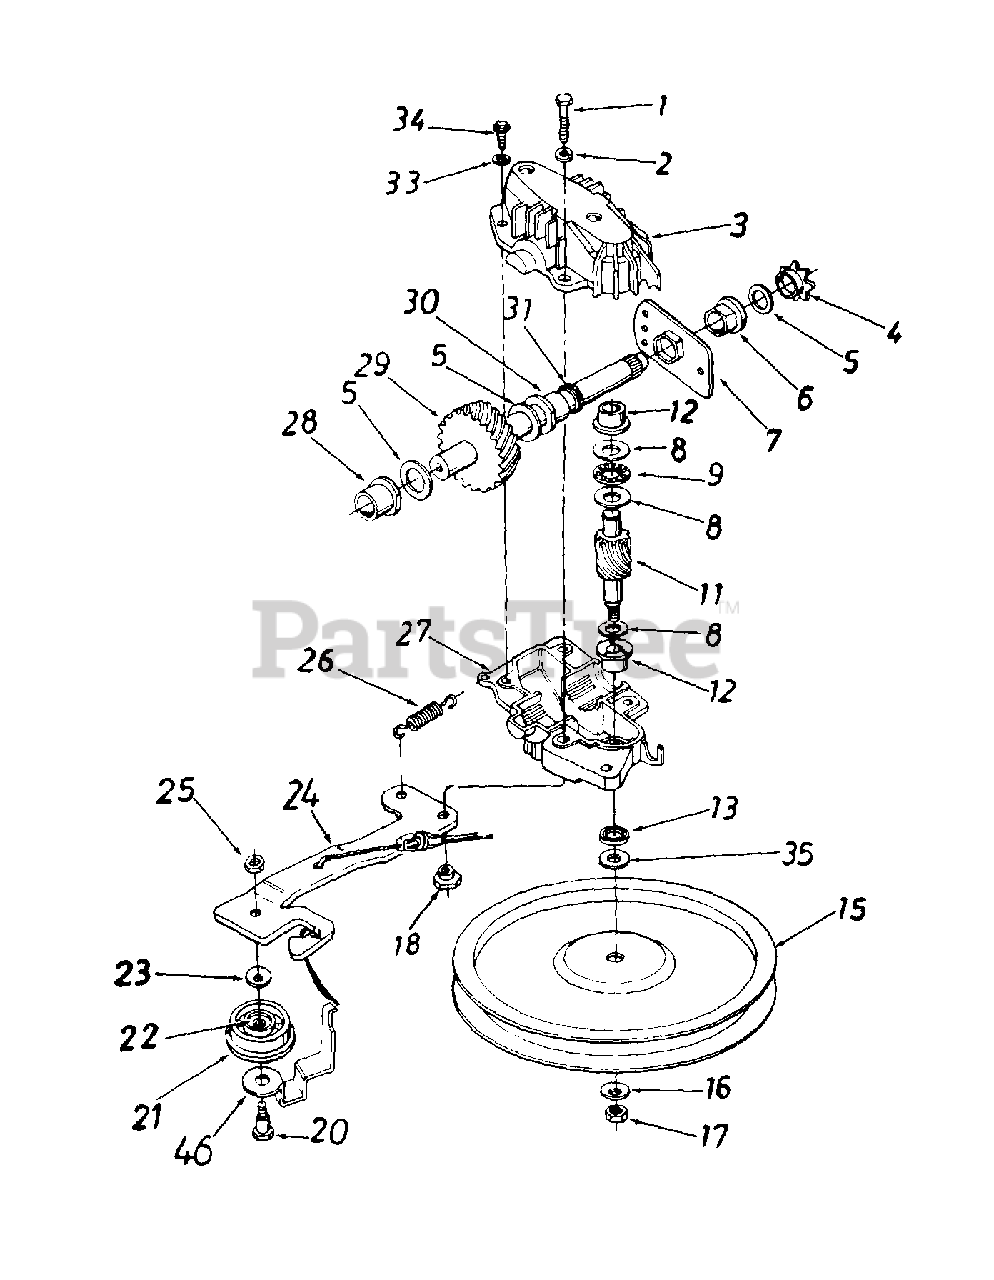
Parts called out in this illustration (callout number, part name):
1	Hex Bolt 1/4-20 x 1.25" Lg. w/Patch
2	L-Wash. 1/4" I.D.
3	Upper Hsg. Half
4	#48 Sprocket 7 Tooth x 1/2 Pitch
5	Fl-Wash. 5/8" I.D. x .030
6	Hex Flange Brg. .631" I.D.
8	Thrust Wash. .382" I.D. x .70" O.D.
9	Thrust Bearing .375" I.D. x .812" O.D.
11	11 Tooth Pinion Shaft
12	Flange Bearing
15	Fl-Pulley 5.06" O.D.
16	Bell-Wash. .265" I.D. x.75"
17	Hex L-Nut 1/4-28 L.N. Thd.
18	Shld. Spacer .375" Dia. x .170
20	Shld. Bolt .375" Dia x .40"
21	Fl-Idler Plastic 1.50" Dia.
22	Needle Brg .375" x 31
23	Bell-Wash. .265" I.D. x 75"
24	Idler Brk't Ass'y
25	Hex Patch L-Nut 1/4-28 Thd.
26	Extension Spring 1.12" Lg.
27	Lower Hsg. Half
28	Flange Bearing .566 Dia.
29	33 Tooth Helical Gear
30	Flange Bearing .629 Dia
31	Oil Seal .625 Dia.
33	L-Wash #10 I.D.
34	Hex Tap Scr #10 x 75" Lg.
35	Hex Washer 236" x 88"
46	Belt Keeper
